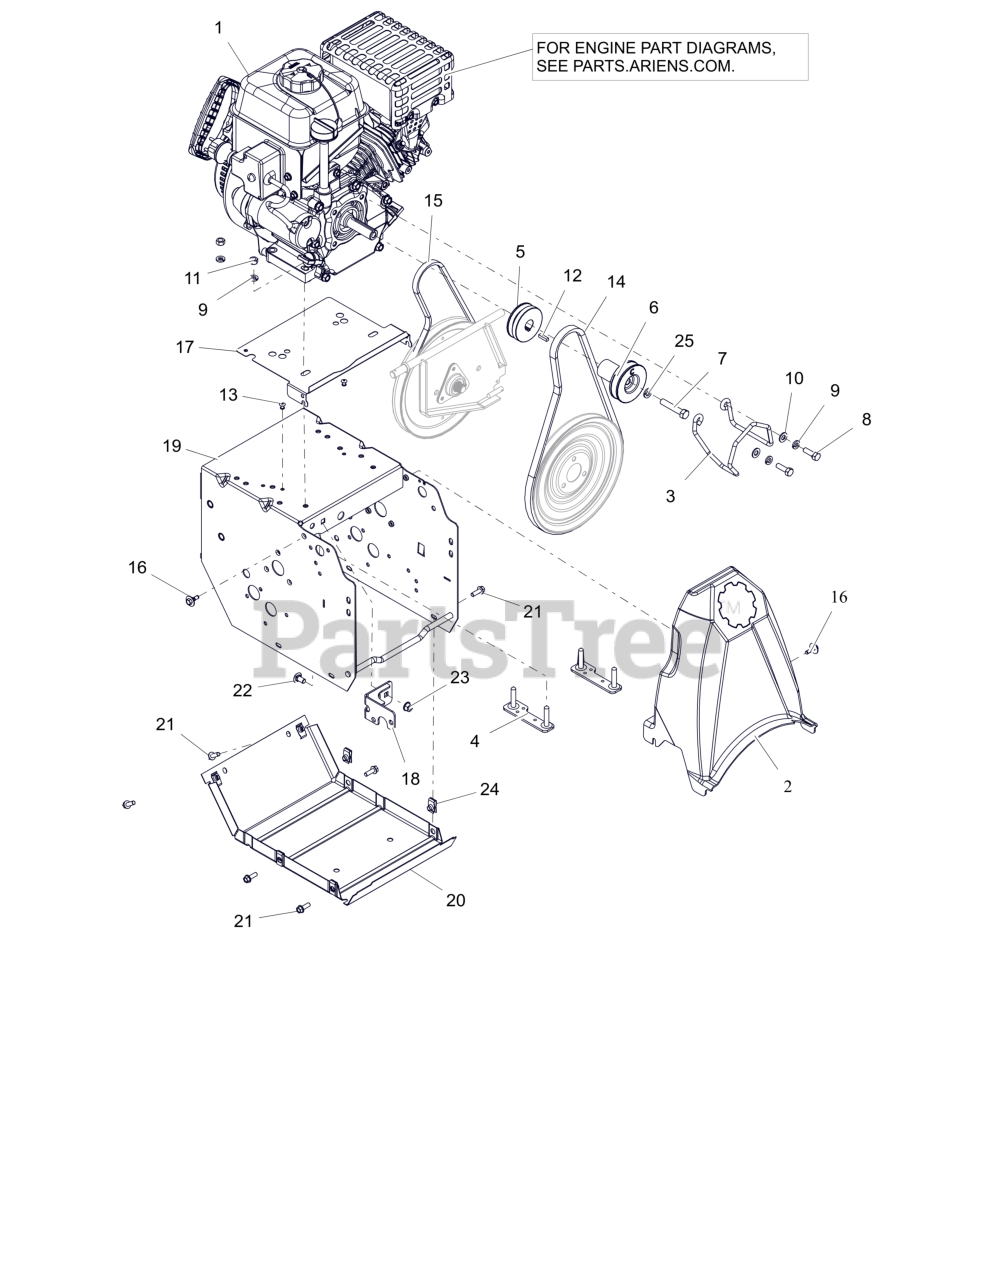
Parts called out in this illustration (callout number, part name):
1	ENGINE, ARIENS AX208 240V/60W
2	COVER- CLASSIC BELT
3	FINGER, BELT
4	STRAP, ENGINE BOLT-WELDMENT
5	SHEAVE, TRACTION-COMPACT TRACK
6	SHEAVE, ATTACHMENT SINGLE GRV
7	BLT, HEX .38-24X2.00 G5 ZCC
8	BLT, HEX 0.3125-24X1 G5 ZCC
9	WSHR, LK-HVY .312X.097 ZCC
10	WSHR,FLT .344X.688X.065 ZCC
11	NUT, HEX .312-18 ZCC
12	KEY-SQ .188X.75X.188
13	RVT, POP .1875 ZCC
14	V-BELT, HA-RAW EDGE
15	V-BELT, 3L-WRAPPED
16	SCR-TAP .25-20X.5 CAPTIVE
17	BAFFLE, COMPACT
18	WELDMENT, FRAME BRACKET
19	FRAME, MAIN-WELDMENT
20	COVER, BOTTOM
21	BLT, HWH .25-20X.75 G5 ZCC
22	BLT, RHSSN .31-18X.625 G5 ZCC
23	NUT-LK-TOP-FLG .312-18 GF ZCC
24	NUT-RTNR .25-20X.56
25	WSHR,LK-REG .375X.094 ZCC
